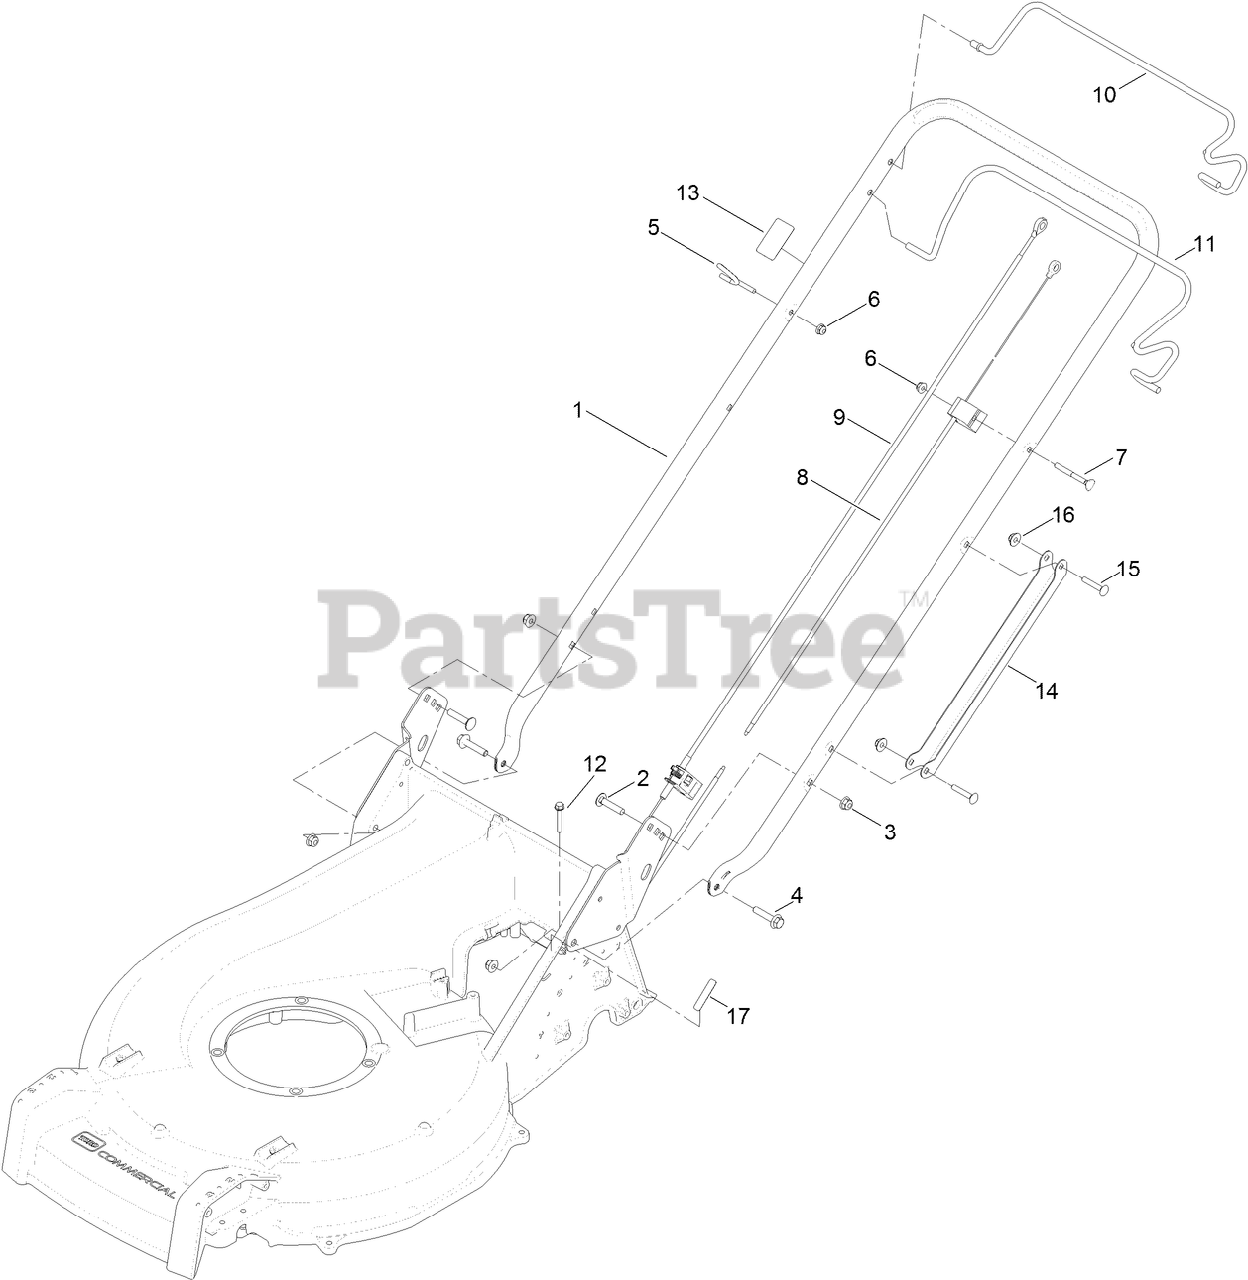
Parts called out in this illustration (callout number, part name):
2	BOLT-CARR
3	NUT-HF, NI
4	SCREW-HHF
5	GUIDE-ROPE
6	NUT-HF
7	SCREW-HANDLE
8	CABLE-BRAKE
9	CABLE-TRACTION
10	BAIL-TRACTION
11	BAIL-BRAKE
12	SCREW-HWH
13	DECAL-PRIMER
14	GUARD-CABLE, HANDLE
15	SCREW-CARR
16	NUT-HF
